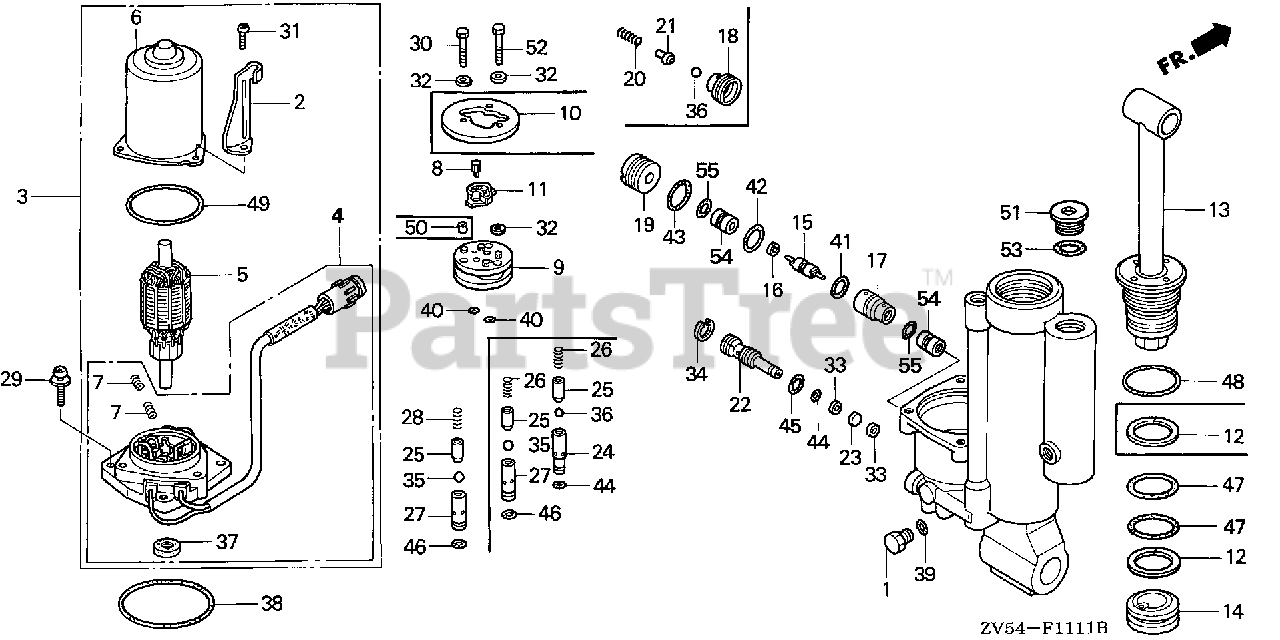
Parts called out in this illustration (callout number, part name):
10	HOLDER, VALVE
11	FILTER, B
11	FILTER B
12	RING, BACK-UP
13	ROD, PISTON
15	SPOOL, VALVE
16	RING, BACK-UP
17	SLEEVE
18	SEAT D, VALVE
19	PLUG C
20	SPRING, CHECK VALVE
21	GUIDE B, SPRING
22	VALVE, MANUAL
23	SEAT, PLATE
24	SEAT, VALVE
25	GUIDE, SPRING
26	SPRING, VALVE
27	SEAT B, VALVE
28	SPRING B, VALVE
30	BOLT, HEX. (5X30)
30	BOLT A, SOCKET
32	WASHER, PLAIN
33	WASHER, SEAL
34	CIRCLIP (INNER)
36	BALL, STEEL
44	O-RING
46	O-RING
50	COLLAR
51	CAP, OIL HOLE
52	BOLT, HEX. (5X30)
52	BOLT B, SOCKET
53	O-RING
54	VALVE (B)
55	O-RING
